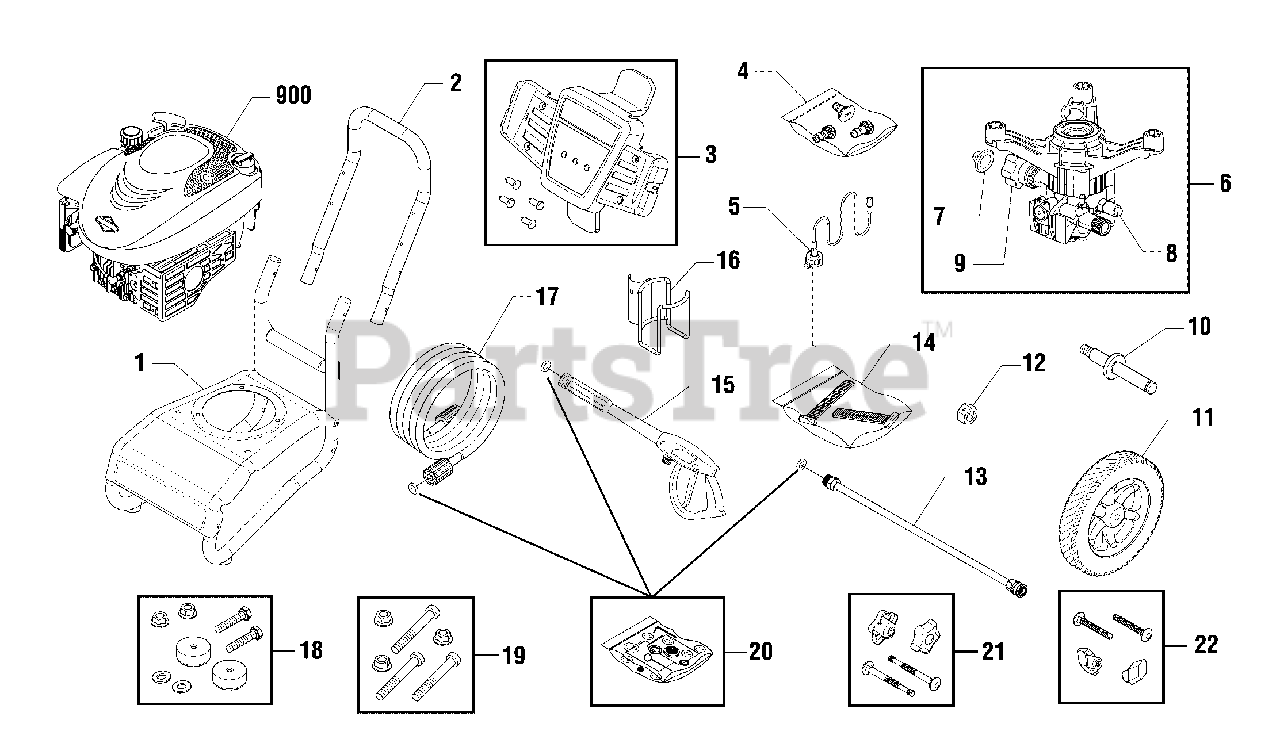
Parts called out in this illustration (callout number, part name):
6	PUMP
7	NOZZLE, QC Black
7	VALVE, Thermal Relief
8	FILTER, Garden Hose
9	ADAPTER, Garden Hose
13	EXTENSION, QC
15	GUN
17	HOSE
18	MOUNT, Vibration
19	KIT, Hardware, Pump Mounting
20	KIT, O-Ring
21	KIT, Hardware, Handle
22	KIT, Hardware, Handle
900	* ENGINE, Briggs & Stratton
